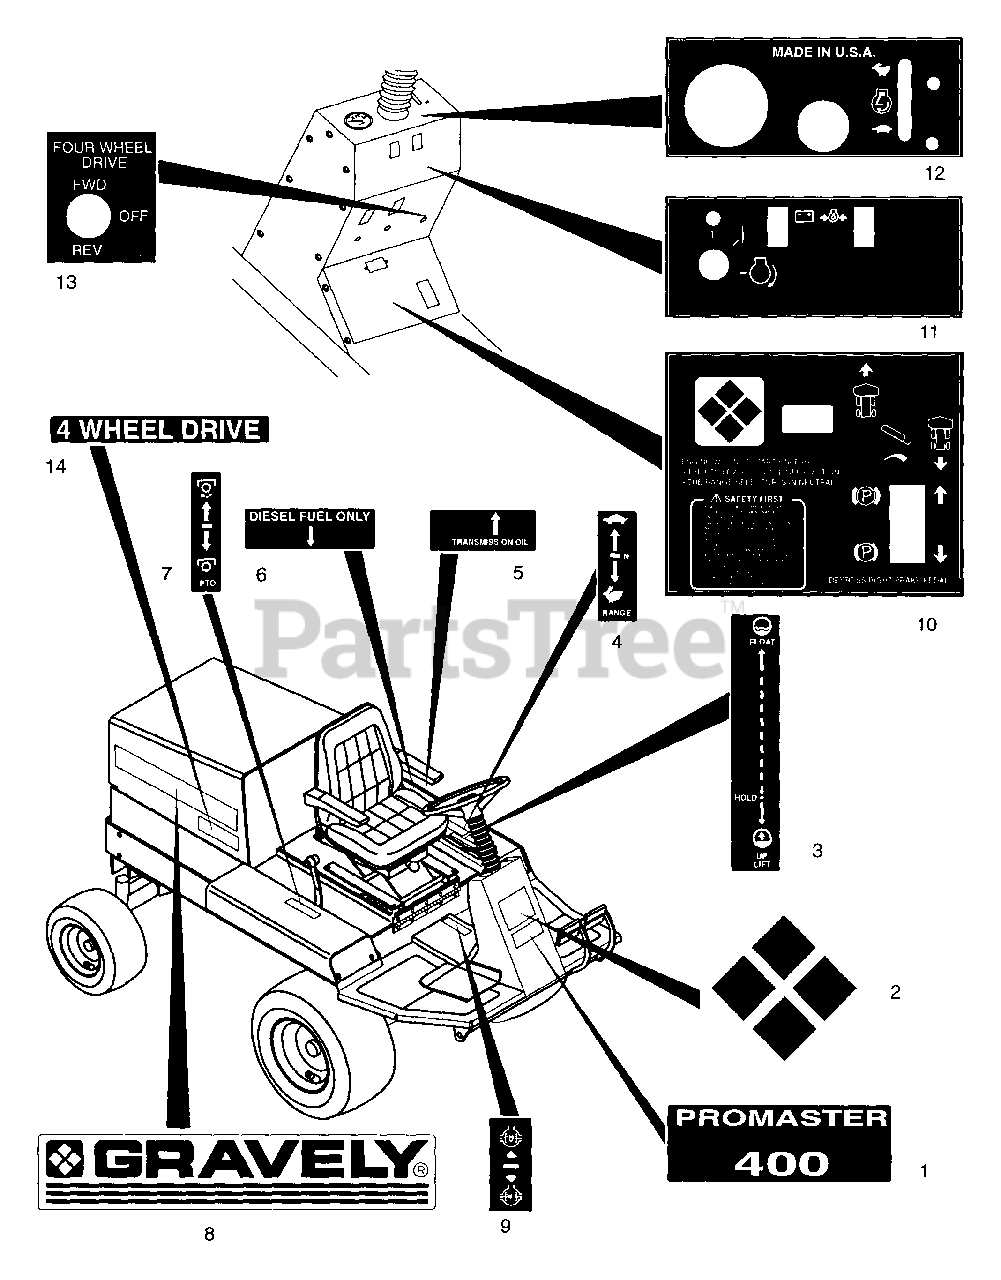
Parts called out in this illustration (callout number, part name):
1	Decal Set
2	Decal Set
3	Decal Set
4	Decal Set
5	Decal Set
6	Decal Set
7	Decal Set
8	Gravely Name/Logo/Stripe Decal
9	Decal Set
10	Decal Set
11	Decal Set
12	Decal Set
13	Four Wheel Drive Decal
14	Decal, Four Wheel Drive (054,302)
